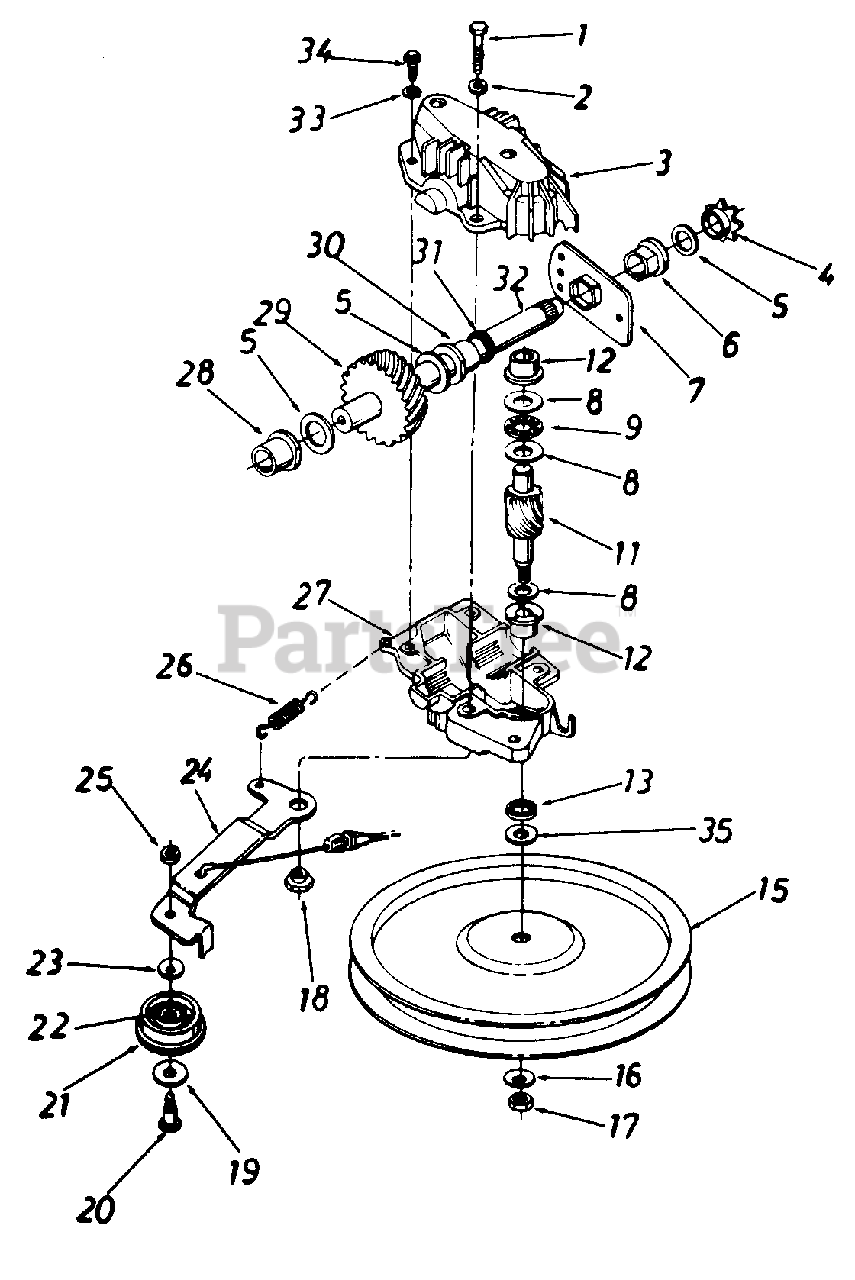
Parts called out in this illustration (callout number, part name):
1	Hex Bolt 1/4-20 x 1.25" Lg. w/Patch
2	L-Wash. 1/4" I.D.
3	Upper Hsg. Half
4	#48 Sprocket 7 Tooth x '/2 Pitch
5	Fl-Wash. 5/8" I.D. x.030
6	Hex Flange Brg. .631" I.D.
8	Thrust Wash. .382" I.D. x .70" O.D.
9	Thrust Bearing .375" I.D. x .812" O.D.
11	11 Tooth Pinion Shaft
12	Flange Bearing
13	Oil Seal
15	Fl-Pulley 5.06" O.D.
16	Bell-Wash. .265" I.D. x 75"
17	Hex L-Nut 1/4-28 L.H. Thd.
18	Shld. Spacer .375" Dia. x .170
19	Fl-Wash. .390" I.D. x 1.0"
20	Shld. Bolt .375" Dia. x .40"
21	Fl-Idler Plastic 1.50" Dia.
22	Needle Brg. .375" x .31t
23	Bell-Wash. .265" I.D. x 75"
24	Idler Brk t. Ass'y.
25	Hex Patch L-Nut 1/4-28 Thd.
26	Extension Spring 1.12" Lg.
27	Lower Hsg. Half
28	Flange Bearing .566 Dia.
29	33 Tooth Helical Gear
30	Flange Bearing .629 Dia.
31	Oil Seal .625 Dia.
32	Gear Sprocket Shaft
33	L-Wash. #10 I.D.
34	Hex B-Tap Scr. #10 x .62"
35	Hex Washer .26" x .88"
